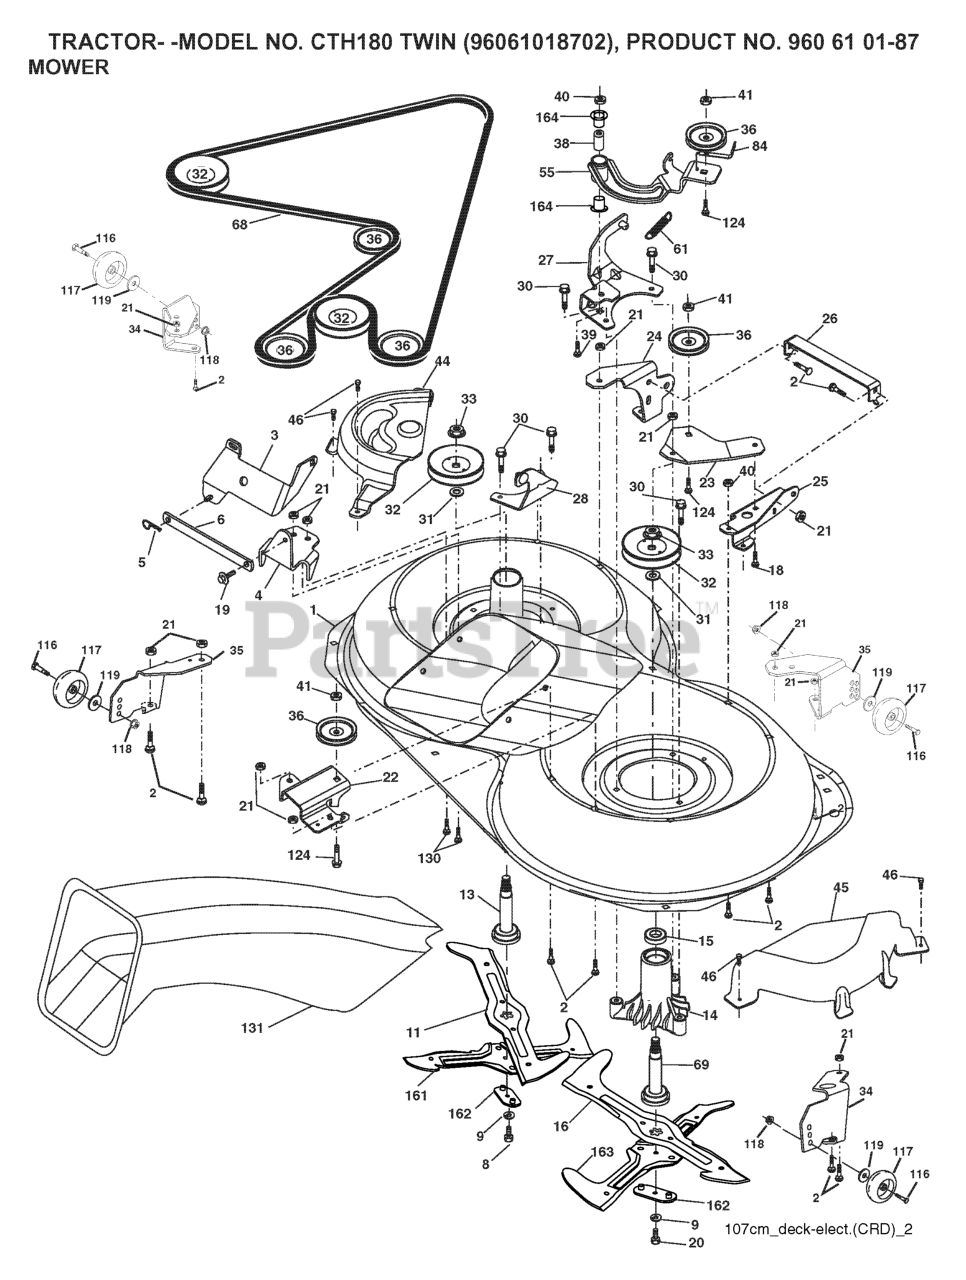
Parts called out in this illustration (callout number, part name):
1	Housing Asm. Mower 107 CRD
2	RP BOLT 5/16-18 X3/4 ZN/YEL GR
5	RETAINER-SPRNG RB
6	BAR.SWAY.92.CRD
8	BOLT.3/8-24X1.25 GR8
9	LOCKWASHER
11	BLADE.3N1.LH.CRD
13	SHAFT ASM VENT
14	HOUSING.MANDREL.VENTED (MACHD)
16	BLADE.3N1.RH.CRD
18	BOLT
19	BOLT SHD 5/16-18
20	BOLT.3/8-24X1.25GR8. LHTHRD
21	LOCKNUT
22	BRACKET.IDLER.RR.107.CRD
24	BRACKET
25	BRACKET RF
26	SUPPORT
28	BRACKET
30	SCREW, WASHER HEAD
31	WASHER.SPACER.MANDREL
32	PULLEY.MANDREL.4.80 PD.2006
33	NUT.FLANGE.LOCK.TOP
34	BRACKET
35	BRACKET
36	PULLEY.IDLER.4.25
41	NUT LOCK FLG 3/8-16 UNC
45	COVER.MANDREL.RH.CRD
46	SCREW.1/4-20X5/8
55	ARM.IDLER.107.CRD
61	SPRING
68	HEX-BELT 107 MOWER
69	SHAFT.ASM.W/LWR.BRG.RH.THREAD
84	KEEPER, BELT IDLER
116	BOLT.SHOULDER.3/8-16X3-5/8.
117	RP WHEEL. GUAGE RALLY
118	NUT LOCK FLG 3/8-16 UNC
119	WASHER
124	BOLT.3/8-16X1.50
130	BOLT.CARR.SQNK.5/16-18UNC.X3/4
131	CHUTE BAGGER
163	BLADE.CROSS.RH.CRD.107
164	BRNG T
